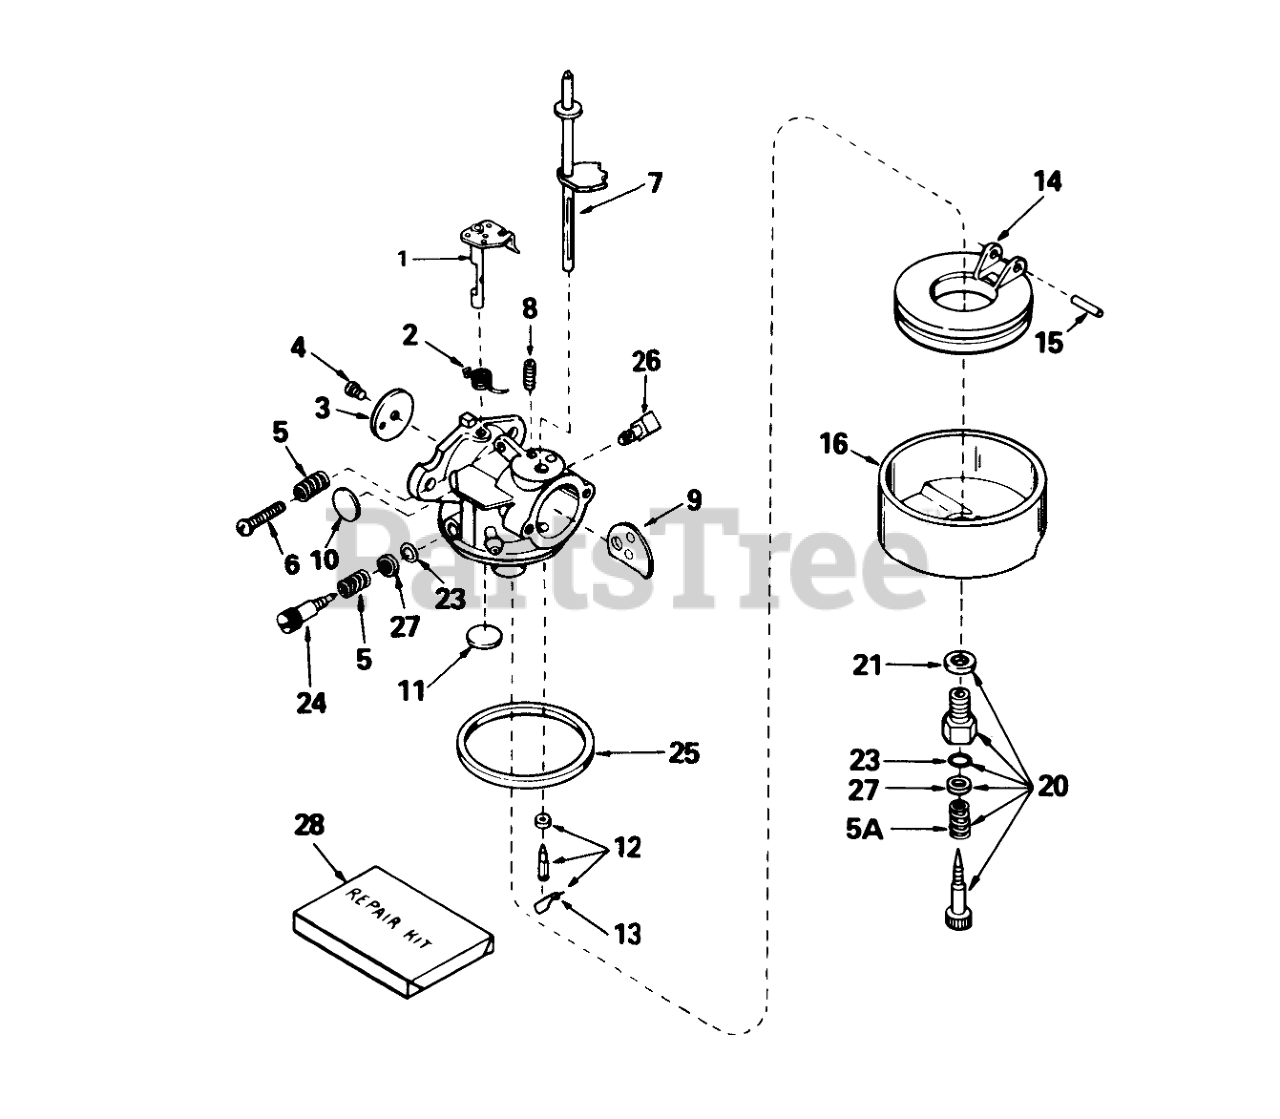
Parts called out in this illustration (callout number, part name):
1	Throttle Shaft and Lever ASM
2	Spring-Return, Throttle
3	Shutter-Throttle
4	Screw-Shutter
5	Spring-Tension
6	Screw-Throttle Crack Screw / Idle Speed
7	Shaft-Choke
8	Spring-Positioning, Choke
9	Shutter-Choke
10	Plug-Welch, Idle Mixture Well
11	Plug-Welch, Atmospheric Vent
12	Inlet Needle-Seat & Clip Assy. (Incl. Ref. #13)
13	Clip-Inlet Needle
14	Float
15	Shaft-Float
16	Bowl-Float (no drain)
20	Adjustment Screw Assy.-Main (Incl. Ref. #5A, 21, 23 & 27)
21	Washer-Bowl Nut
23	"O"Ring
24	Screw, Idle Adj.
25	O Ring-Bowl, Float
26	Fitting-Fuel
28	Kit-Repair
